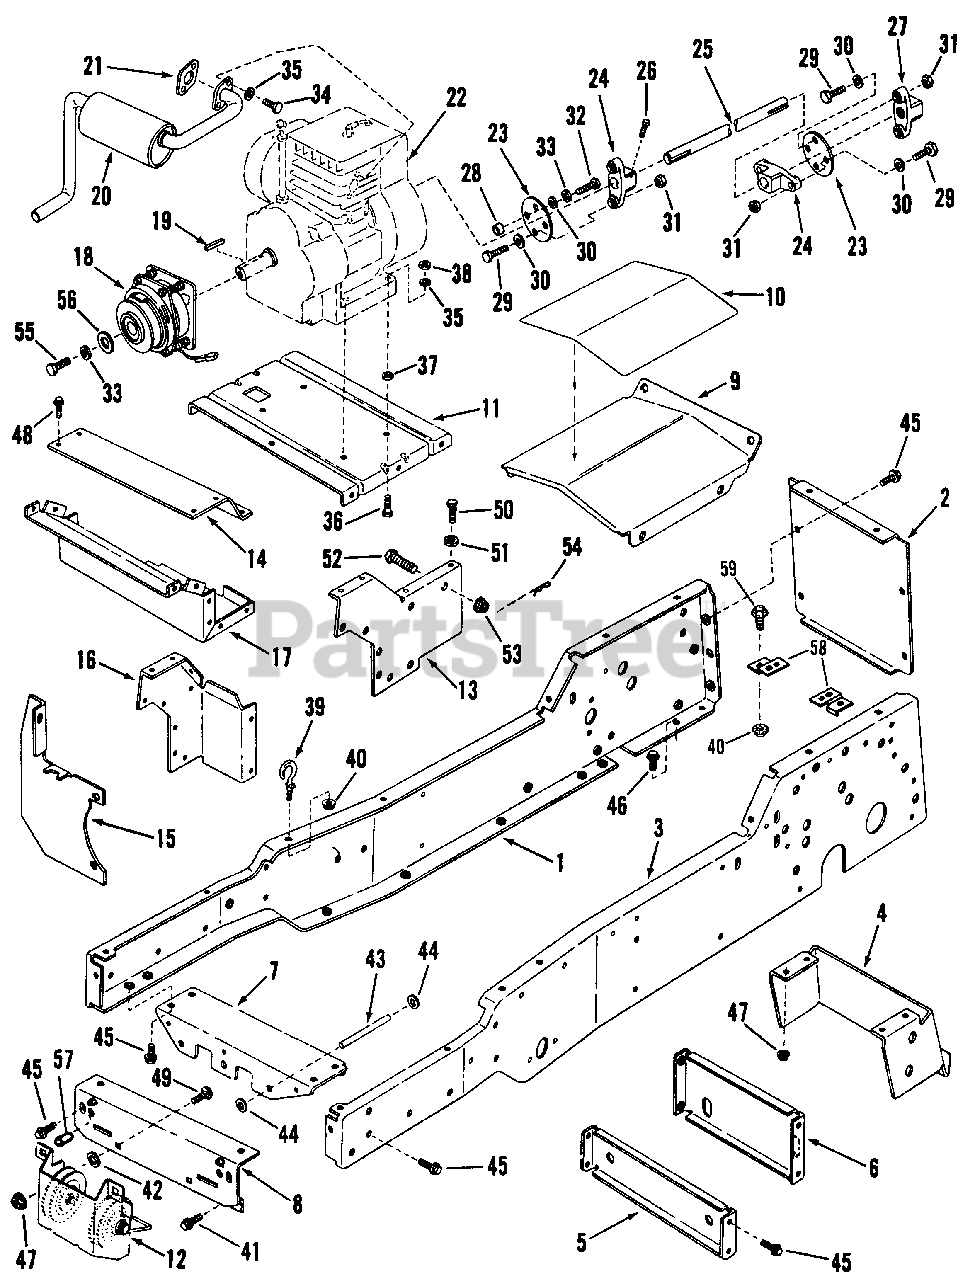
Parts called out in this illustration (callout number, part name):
1	CHANNEL, R. H. Frame (NLA)
1	CHANNEL, R. H. Frame '85 (NLA)
2	PLATE, Rear Cover
2	PLATE, Rear Cover '85
3	CHANNEL, L.H. Frame (NLA)
4	DRAWBAR
5	BRACE, Forward
6	BRACE, Rear Cross (NLA)
7	CHANNEL, Front Axle Support
8	PLATE, Front Axle Support (NLA)
8	PLATE, Front Frame '85 (NLA)
9	COVER, Console
10	DECAL, Console Cover
11	BASE, Engine (NLA)
12	ASSEMBLY, Mule Drive
13	DUCT, Engine Heat-Left Side (NLA)
14	DUCT, Engine Heat-Top (NLA)
15	SHIELD, Heat Duct (NLA)
16	DUCT, Engine Heat-Right Side (NLA)
17	DUCT, Engine Heat-Bottom (NLA)
18	KIT, Electric Clutch
19	KEY, Square (Clutch) (NLA)
20	MUFFLER, LT11 Engine
21	GASKET, Exhaust
22	* ENGINE, 11 HP Briggs Mod 253417-1131-01
23	DISC, Flex Coupling
24	HUB, Flex Coupling
25	SHAFT, Drive 3/4 x 23-7/8"
26	SET-SCREW, 5/16-18 x 1/2"
27	HUB, Flexible Coupling
28	SPACER, Flexible Coupling
29	SCREW, 3/8-16 x 1" HHC
30	WASHER, 3/8" Flat
31	NUT, 3/8-16 Center Lock
32	SCREW, 3/8-16 x 1-1/4" Hex Head Cap, Grade 5
33	WASHER, 3/8 Split Lock
34	SCREW, 5/16-18 x 5/8" Hex Head Cap
35	WASHER, 5/16 Split Lock
36	SCREW, 5/16-18 x 1-3/4" Hex Head Cap
37	RETAINER, 5/16 Bolt
38	NUT, 5/16-18 Hex
39	HOOK, Hood Latch
40	NUT, 5/16-18 Hex Flange Lock
41	SCREW, 1/4-20 x 5/8" Hex Washer Self-Tap
42	RETAINER, 3/8 Bolt
43	STOP, Axle
44	RETAINER, 3/8 Shaft
45	SCREW, 5/16-18 x 5/8" Hex Washer Self-Tap
46	BOLT, 3/8-16 x 3/4" Hex Flange Lock
47	NUT, 3/8-16 Hex Fl. Lock
48	SCREW, #10-24 x 1/2" Hex Washer Self-Tap (Torx)
49	BOLT, 3/8-16 x 3/4" Square Neck Carriage
50	SCREW, 1/4-20 x 5/8" Hex Hex Head Cap
51	WASHER, 1/4 Split Lock
52	BOLT, 1/4-20 Hex Head Drilled
53	NUT, 1/4-20 Hex Flange, Gr. A
54	PIN, 1/4 Hair
55	SCREW, 3/8-24 x 1" Hex Cap, Grade 5
56	WASHER, Pull Bar
57	RELIEF, Strain
58	BRACKET, Rear Fender Mtg.
59	BOLT, 5/16-18 x 1" Hex Flange Lock Bolt
